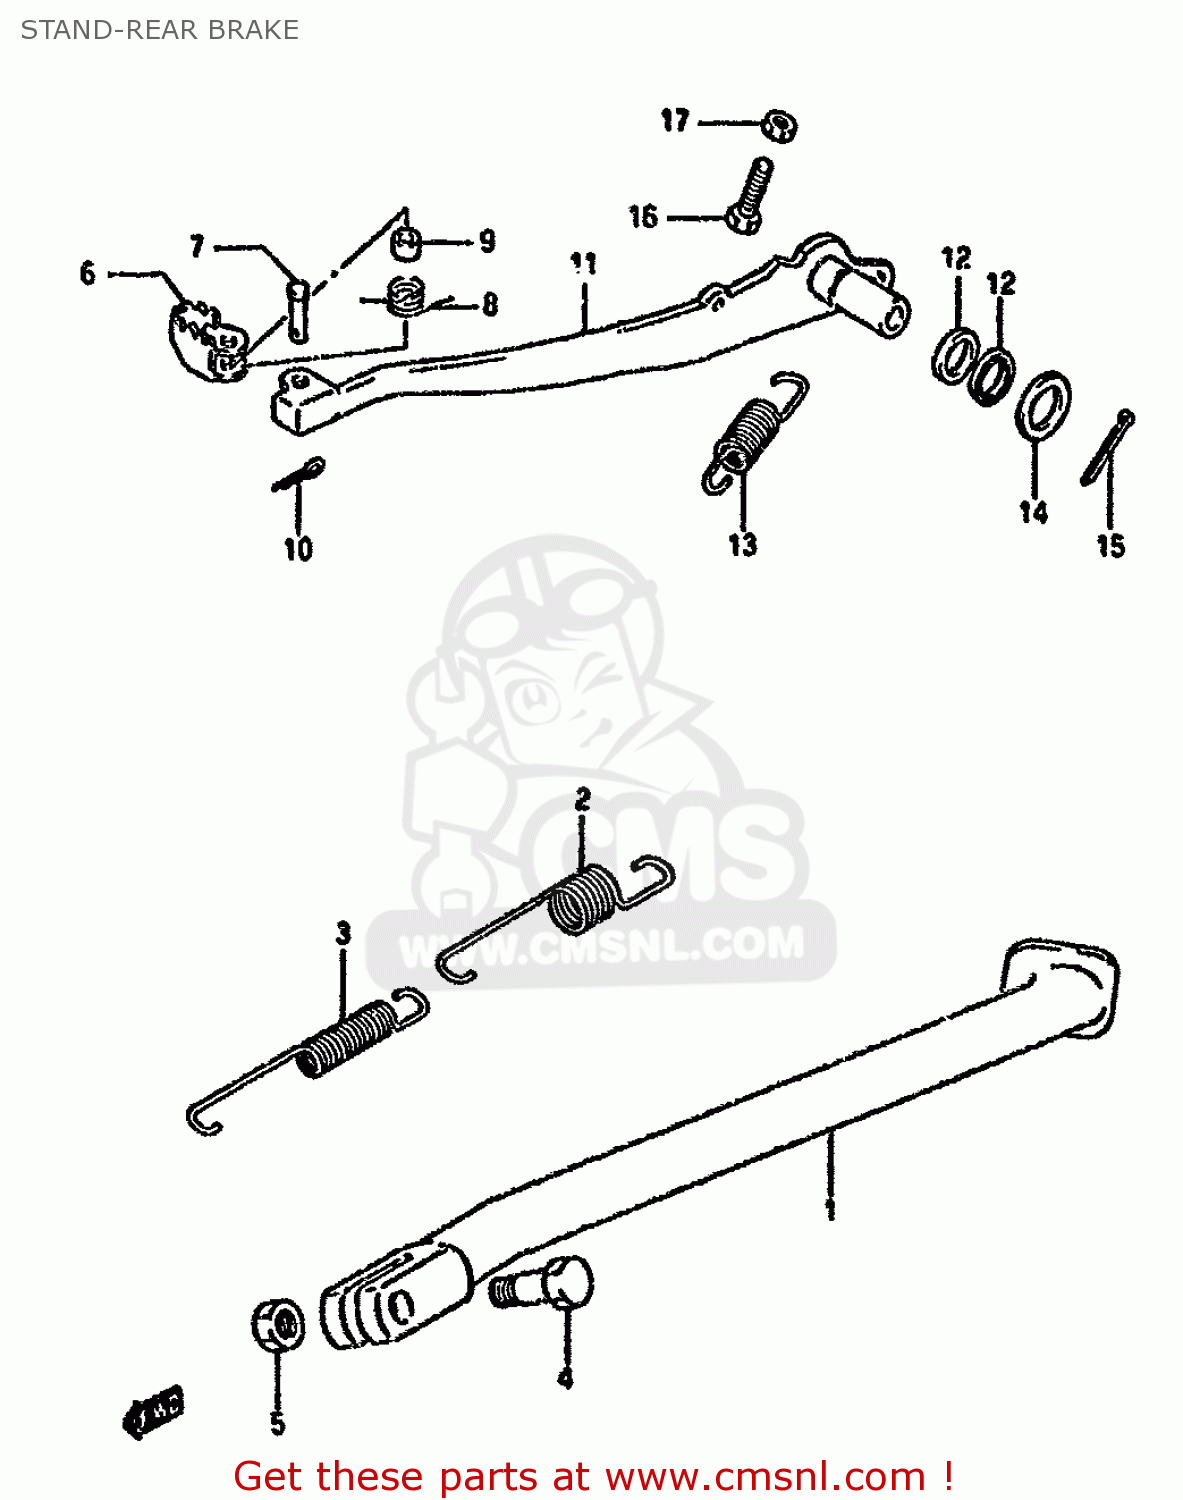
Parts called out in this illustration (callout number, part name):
1	STAND,SIDE
2	SPRING
3	SPRING
4	BOLT(10X30)
5	NUT
6	PEDAL,BRAKE
7	PIN
8	SPRING
9	SPACER(9.2X9X6.5)
10	PIN
11	ARM,BRAKE PEDAL
12	SEAL,OIL(15X21X3)
13	SPRING
14	WASHER(15.5X26X2.3)
15	COTTER PIN
16	BOLT(6X23)
17	NUT 6MM
